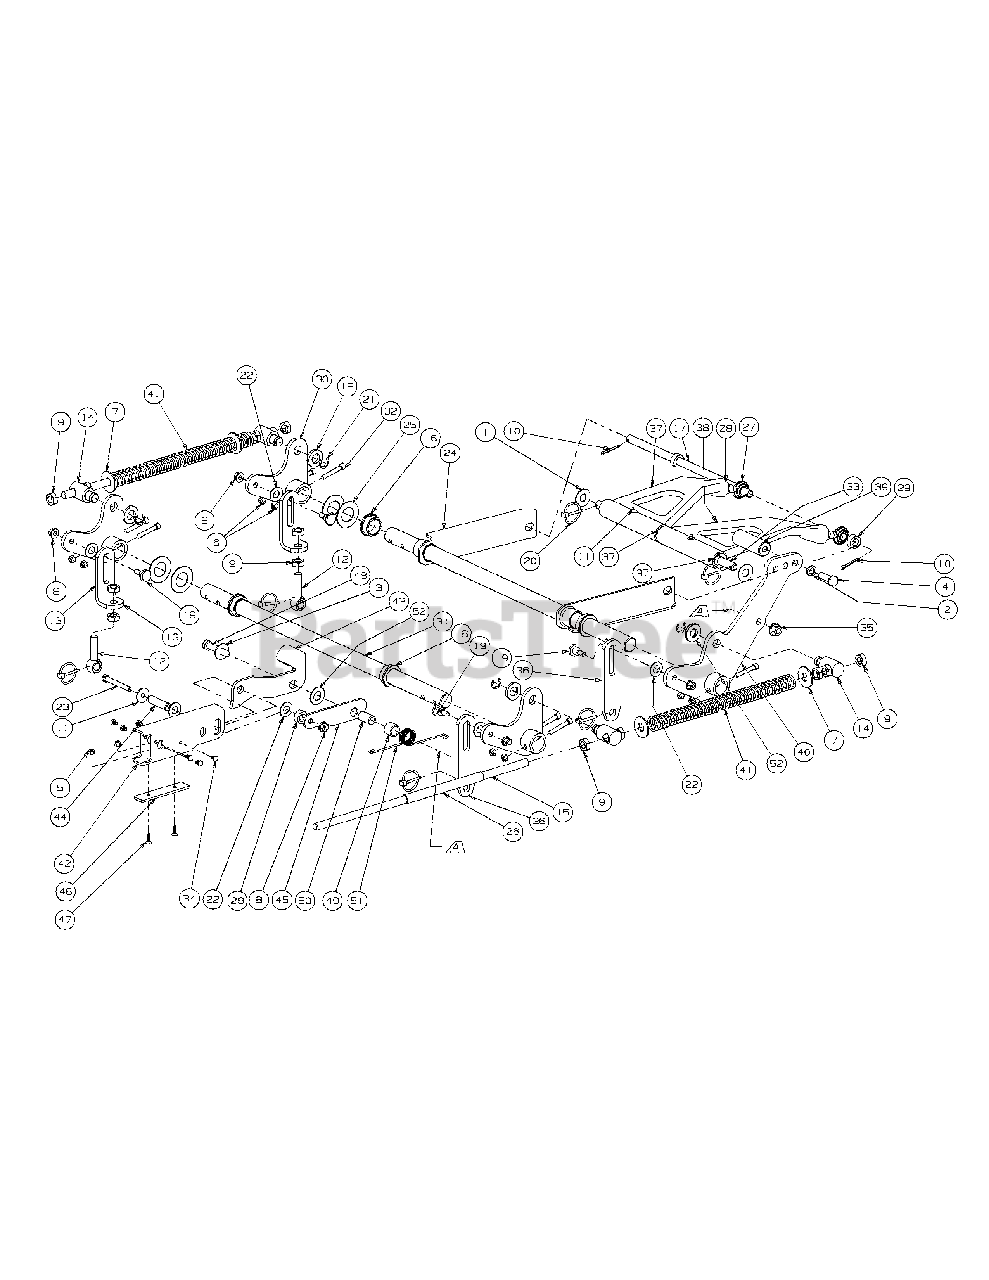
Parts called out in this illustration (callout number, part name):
1	Washer, 1.5 x .655 x .055
2	Lock Washer, 1/2
3	Flat Washer, 1/2
4	Hex Cap Screw, 1/2-13 x 1.50
5	Lock Nut w/Nylon Insert
6	Nut, 5/16-18, Nylock
7	Flat Washer, 5/8
8	Hex Nut, Flange Lock, 3/8-16
9	Jam Nut, 5/8-11
10	Cotter Pin, 3/16 x 1-1
11	Flat Washer, 1.25 x .411 x .100
12	Eye Bolt, 5/8ID
13	Eye Bolt Mount Link, 5/8 ID
14	Ferule Lift
15	Lift Connector Rod
16	Hex Flange Bearing, 1.25 ID
17	Front Lift Link, Rod Mount
18	Spacer, .812 ID x .268 Lg.
19	Shoulder Screw, 0.625 OD x .437 Lg.
20	Linch Pin, 3/16 Dia.
21	E Clip, 3/4 Dia.
22	Nylon Flat Washer, 5/8
23	HHCS, 3/8-16, 3.00
24	Front Frame Strut Assembly
25	Flat Washer, 1.25 ID
26	Hose, 5/8 ID 13/16 OD, 8" LG
27	Rod End, Male
28	Jam Nut, 5/8-18
29	Spacer, .630 ID x 1.06 OD x .440
30	Bellecrank Weldment Assembly
31	Deck Lift Shaft
32	Socket Head CapScrew, 5/16-18 x 2
33	Lift Link Rod
34	Rivet, 1/4 x 5/8
35	Nut, 1/2-13, FlangeLock
37	Bearing Lift Brace Assembly, Left Hand includes:
38	Bearing Lift Brace Assembly, Right Hand includes:
39	Deck Lift Foot Pedal
40	Deck Lift Foot Pedal Weldment
41	Lift Compression Spring
42	Lift Tube, 3.0 x 1.5
43	Lift Link Bracket
44	Spacer, .375 ID x .625 OD x 1.53
45	Yoke Plate
46	Lift Wear Plate
47	Flat Head Cap Screw, 1/4-20 x .75
48	HHCS, 1/2-13 x 2.50
49	Spacer, .76 ID x 1.0 OD x .75
50	Spacer, .50 ID x .75 OD x 1.313
51	Torsion Spring, .120 Wire x 1.32 OD
52	Washer, .76 x 1.49 x .06
